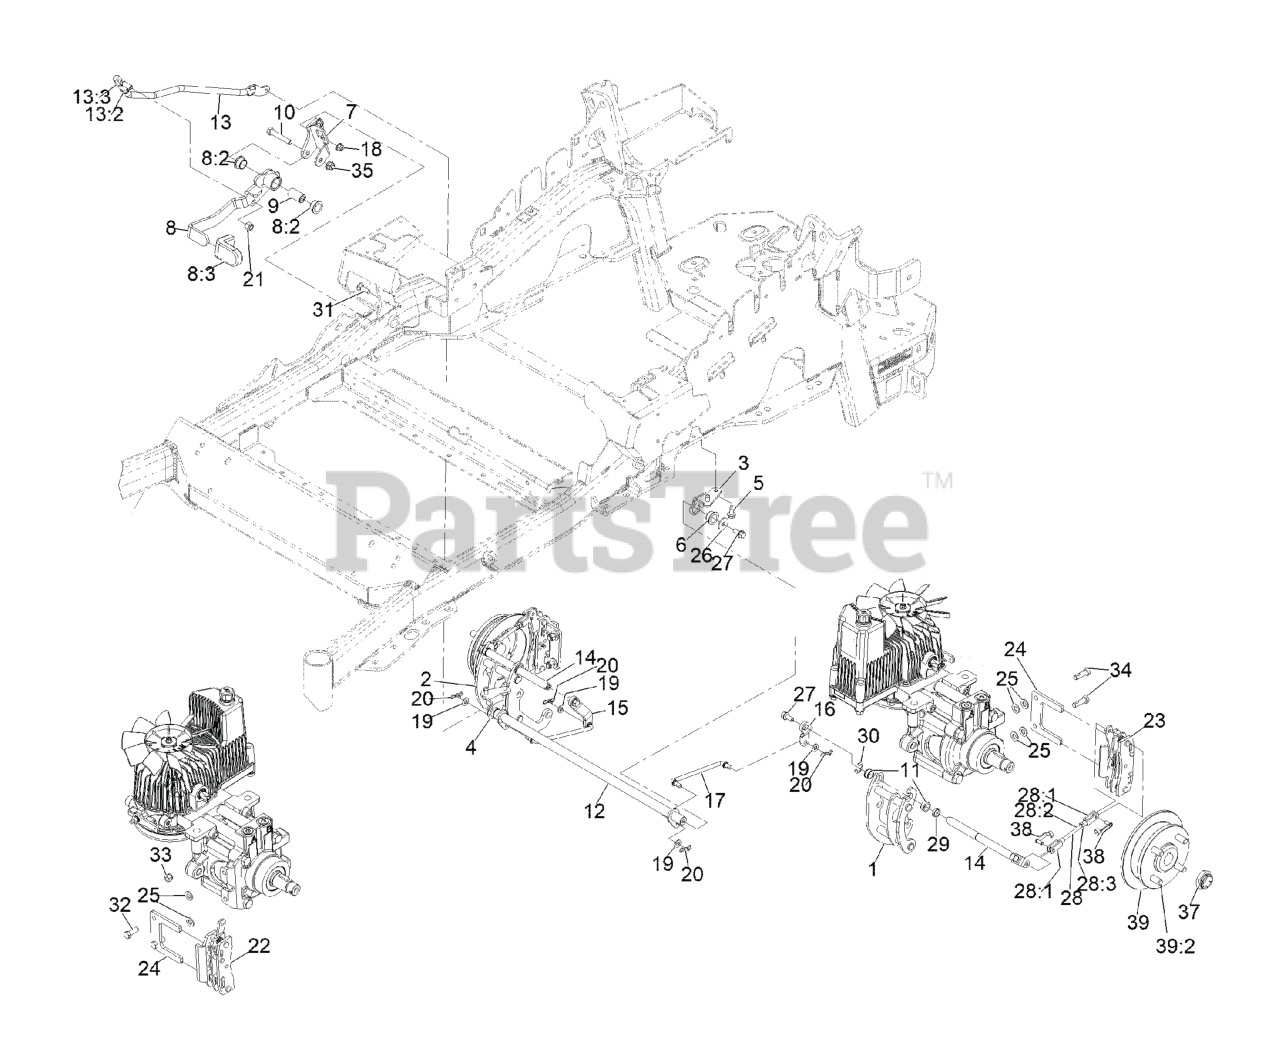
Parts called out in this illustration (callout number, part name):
1	MOUNT-BELLCRANK, LH
2	MOUNT-BELLCRANK, RH
3	MOUNT-PIVOT, LH
4	MOUNT-PIVOT, RH
5	Screw-HWH 5/16-18 X 3/4 Tf
6	BUSHING-FLANGE
7	BRACKET-MOUNT
8	Brake Lever ASM
8:2	BUSHING-FLANGE
8:3	GRIP-LEVER
9	HANDLE-PIVOT, BRAKE
10	SCREW-HH
11	BUSHING
12	Shaft-Cross
13	ASM, Front Linkage
13:2	END-TIE ROD, RH
13:3	NUT-HJ
14	BELLCRANK
15	ARM-INNER, RH
16	ARM-INNER, LH
17	Link-Mid
18	NUT-HF, NI
19	WASHER-PLAIN
20	PIN-COTTER, LOCKING
21	NUT-LOCK
22	Caliper-Brake, RH
23	Caliper-Brake, LH
24	PLATE-MOUNT, BRAKE
25	WASHER-FLAT
26	WASHER-FLAT
27	SCREW-HHF
28	REAR LINKAGE ASM
28:3	NUT-JAM
31	BOLT-CARR
32	SCREW-HH,
33	NUT-LOCK
34	Screw-HH, Patch
35	NUT-HF, NI
37	LOCKNUT
38	PIN-CLEVIS, SPRING
39	Wheel Hub ASM
39:2	STUD-WHEEL
